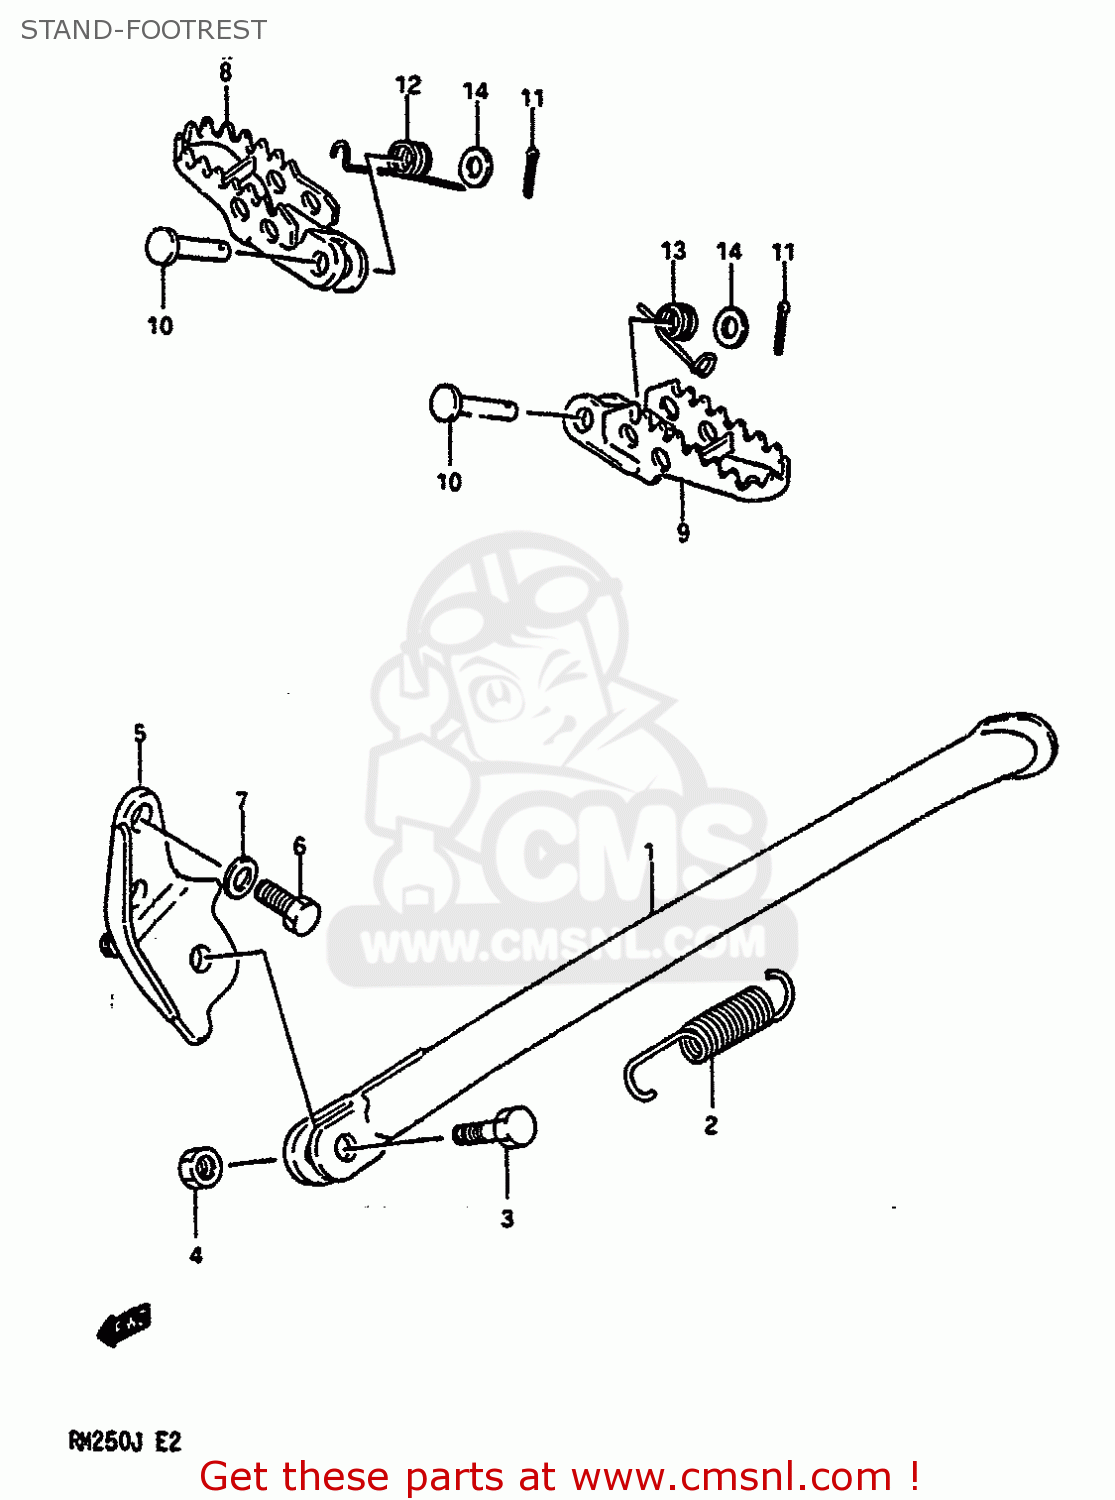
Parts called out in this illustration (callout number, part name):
1	STAND,SIDE
2	SPRING
3	BOLT(10X30)
4	NUT
5	BRACKET,SIDE STAND
6	BOLT(10X19)
7	WASHER,LOCK,10
8	FOOTREST,FRONT,RIGHT
9	FOOTREST,FRONT,LEFT
10	PIN
11	PIN 25X20
12	SPRING
13	SPRING
14	WASHER
